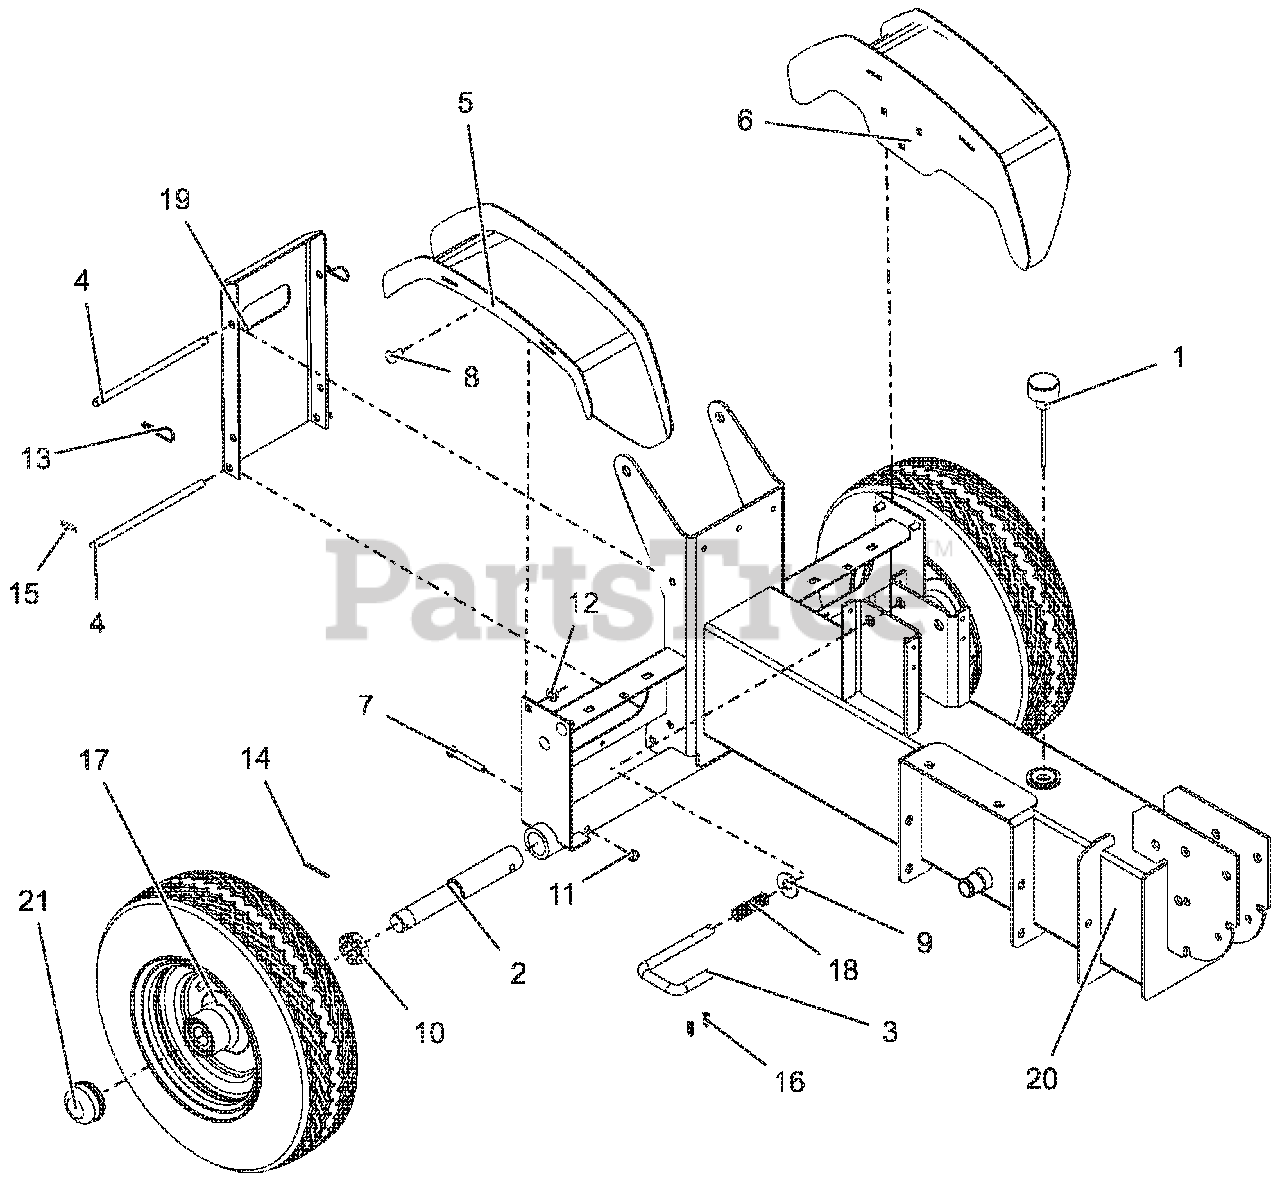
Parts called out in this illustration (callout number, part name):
1	BREATHER, DIPSTICK
2	AXLE, SPLITTER
3	LOCK, BEAM
4	PIN, .373 X 7.30 X 2X .109 THRU (BLACK)
5	WLDMT, FENDER -RH (ORANGE)
6	WLDMT, FENDER -LH (ORANGE)
7	BLT-HEX .31-18X2.25 GR5 YWZC
8	BLT-RDHDSQNK .31-18X.75 G5 YWZC
9	WSHR-FL-STL.563X1.38X.109YWZC
10	NUT, SL 1.0-14
11	NUT-LK-CTR .31-18 YWZC
12	NUT, LK-TOP-FLG .312-18 YWZC
13	HAIR, PIN #7 CLIP .094 X 2.31 YWZ
14	PIN, CTR .15 X 1.50 YWZC
15	PIN-HAIR, ENDRIES #25 YWZC
16	CLIP, SPRING
17	ASSM TIRE\WHEEL, 4.80/4.00-8 P47 GRAY
18	SPRG, COMPRESSION .058X.65X2.13
19	SUPPORT, REAR LEG
20	WLDMT, CHASSIS -SPLITTER (ORANGE)
21	CAP, DUST
